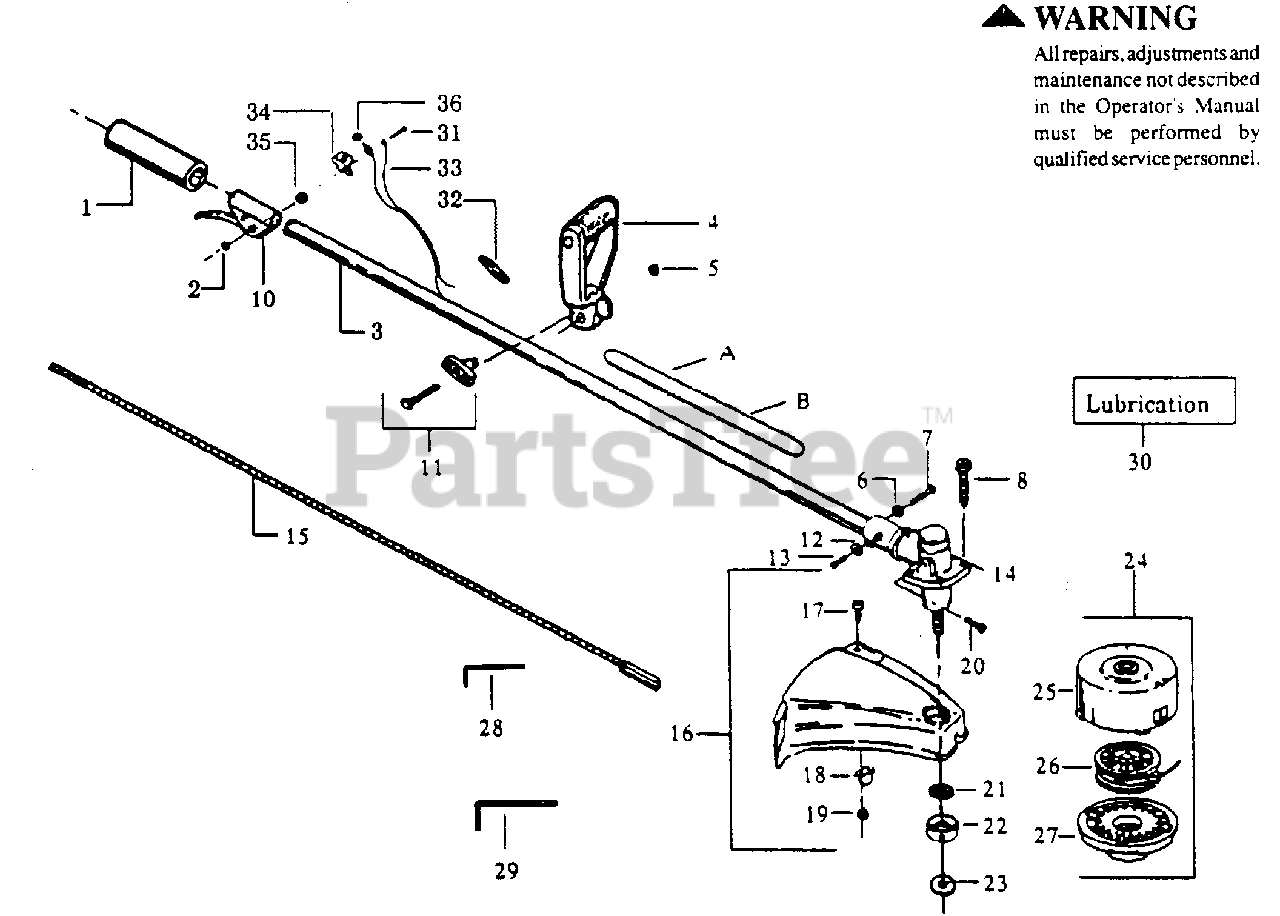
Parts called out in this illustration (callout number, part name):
1	Drive Shaft Grip
3	Drive Shaft Housing
6	Lockwasher
8	Screw
10	Throttle Lever Assy. w/Lock (Inc.2 & 9)
11	"T" Handle Assy.
12	Lockwasher
14	Gear Box Assy.
15	Drive Shaft
16	Shield Kit Assy. (Inc.17 - 19)
18	Line Limiter
19	Locknut
22	Dust Cup
23	Grass Washer
24	Cutting Head Assy. (Inc.25 - 27)
25	Hub Assy.
26	Spool w/Line
28	Hex Wrench (5/32)
29	Hex Wrench (3/16)
30	Shaft Lubrication
32	Terminal Lock
33	Wire Harness Assy.
34	Kill Switch Bracket
36	Nut
